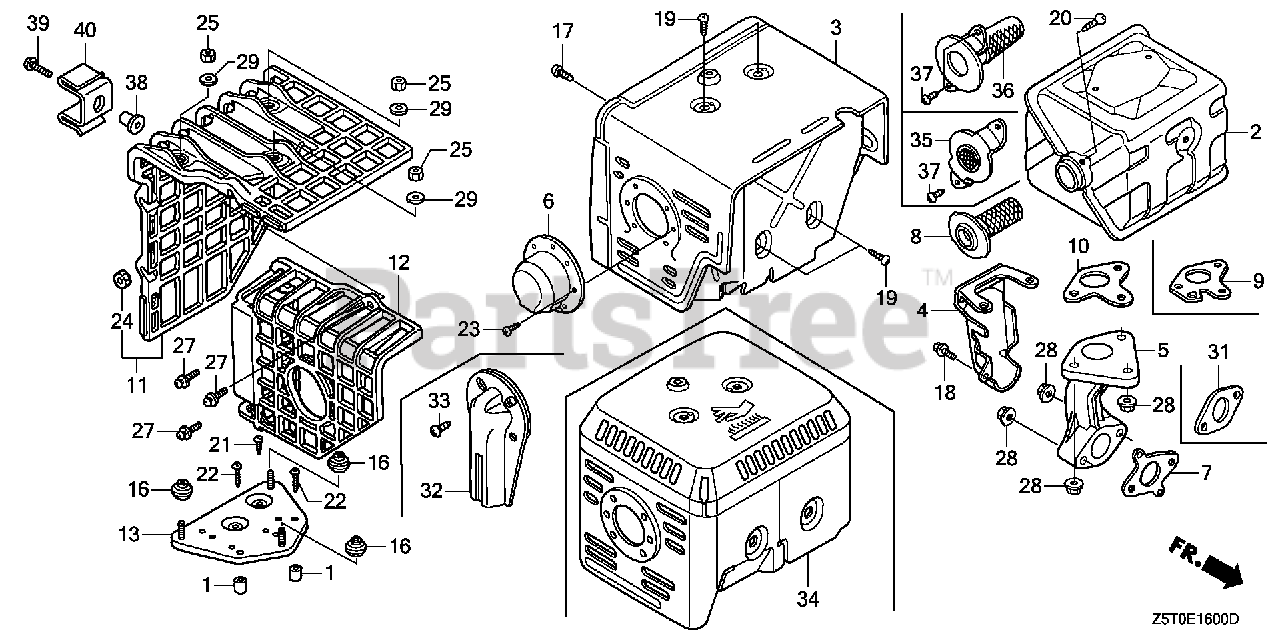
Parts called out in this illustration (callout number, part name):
2	MUFFLER (100DB)
3	PROTECTOR, MUFFLER
4	PROTECTOR, EX. PIPE
6	CAP, MUFFLER
7	GASKET, EX. PIPE
8	ARRESTER, SPARK
9	GASKET, MUFFLER (ARRESTER)
10	GASKET, MUFFLER (NIPPON LEAKLESS)
10	GASKET, MUFFLER (THAI LEAKLESS)
17	SCREW, TAPPING (6X10)
18	BOLT, FLANGE (6X12) (CT200)
19	SCREW, TAPPING (5X8)
20	SCREW, TAPPING (4X6) (TO INSTALL OPTIONAL SPARK ARRESTER)
23	SCREW, TAPPING (4X6) (TO INSTALL OPTIONAL SPARK ARRESTER)
28	NUT, FLANGE (8MM)
